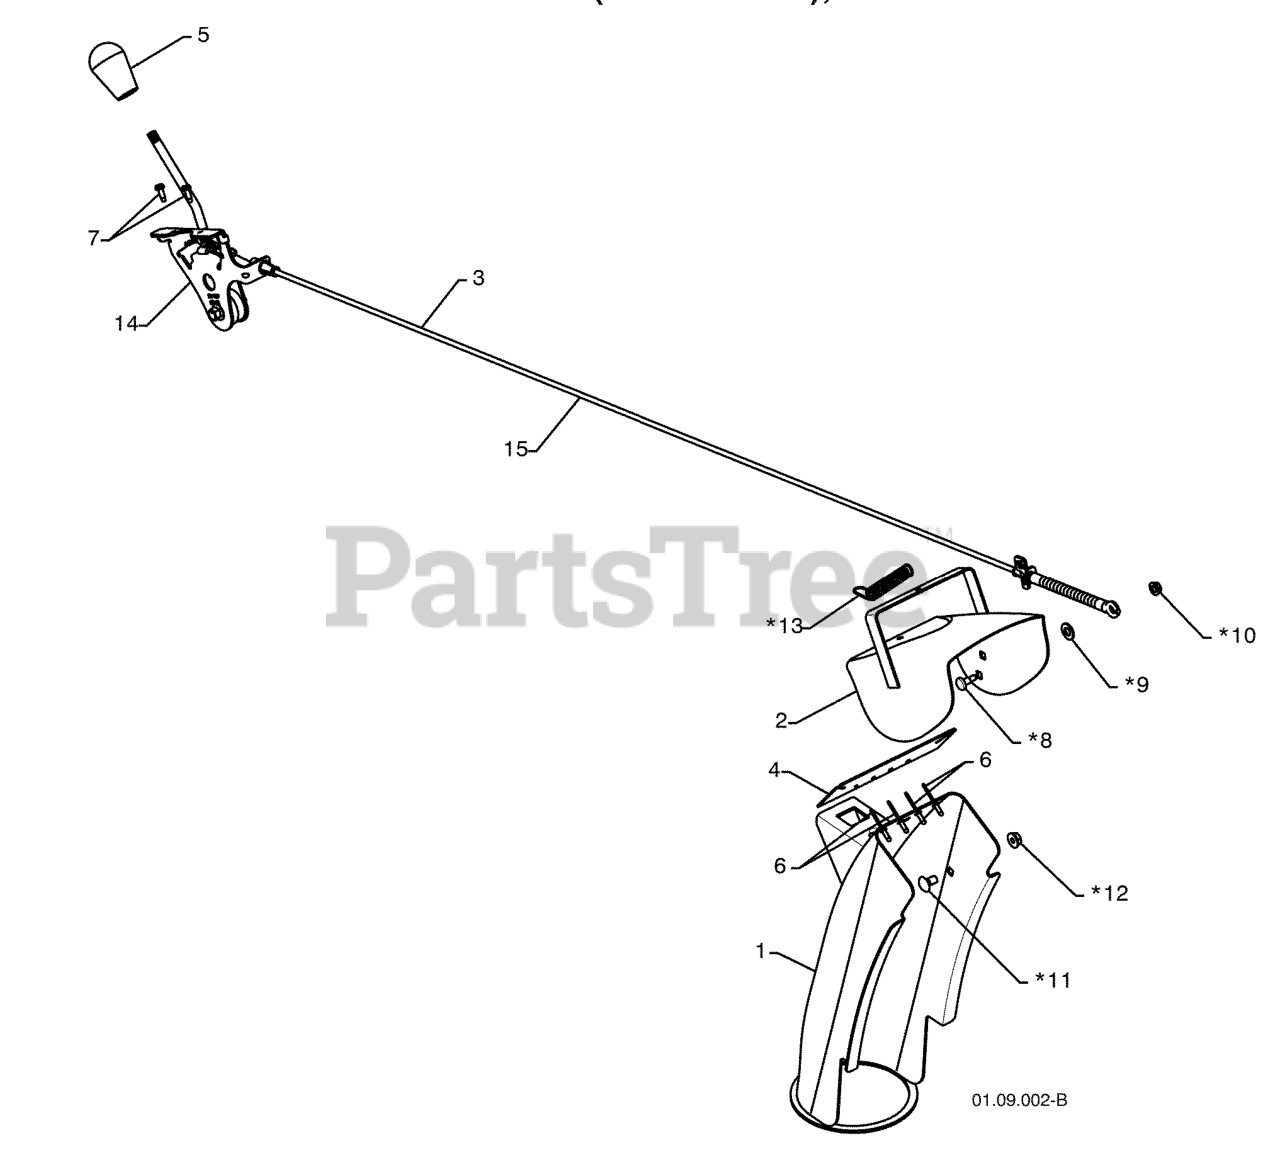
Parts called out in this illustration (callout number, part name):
1	CHUTE ASSEMBLY
2	DEFLECTOR.WELDMENT.PNT.ORANGE
3	RP.CONTROL.ASM.DEFLECTOR.SNOW
4	SEAL.DEFLECTOR
5	KNOB LEVER, BLACK
6	RIVET BLIND
7	SCREW #10-24 X 5/8
8	BOLT, SHOULDER
9	WASHER, NYLON FRICTION
10	NUT.HEX.FLANGE.1/4
11	BOLT
12	NUT.LOCK.5/16-18
13	SPRING.DEFLECTOR.REM.CHUTE
14	RP CNTRL.HEAD.ASSEM.DEFLECTOR
15	RB SERVICE.CHUTE.DEF.CBL.BLK
